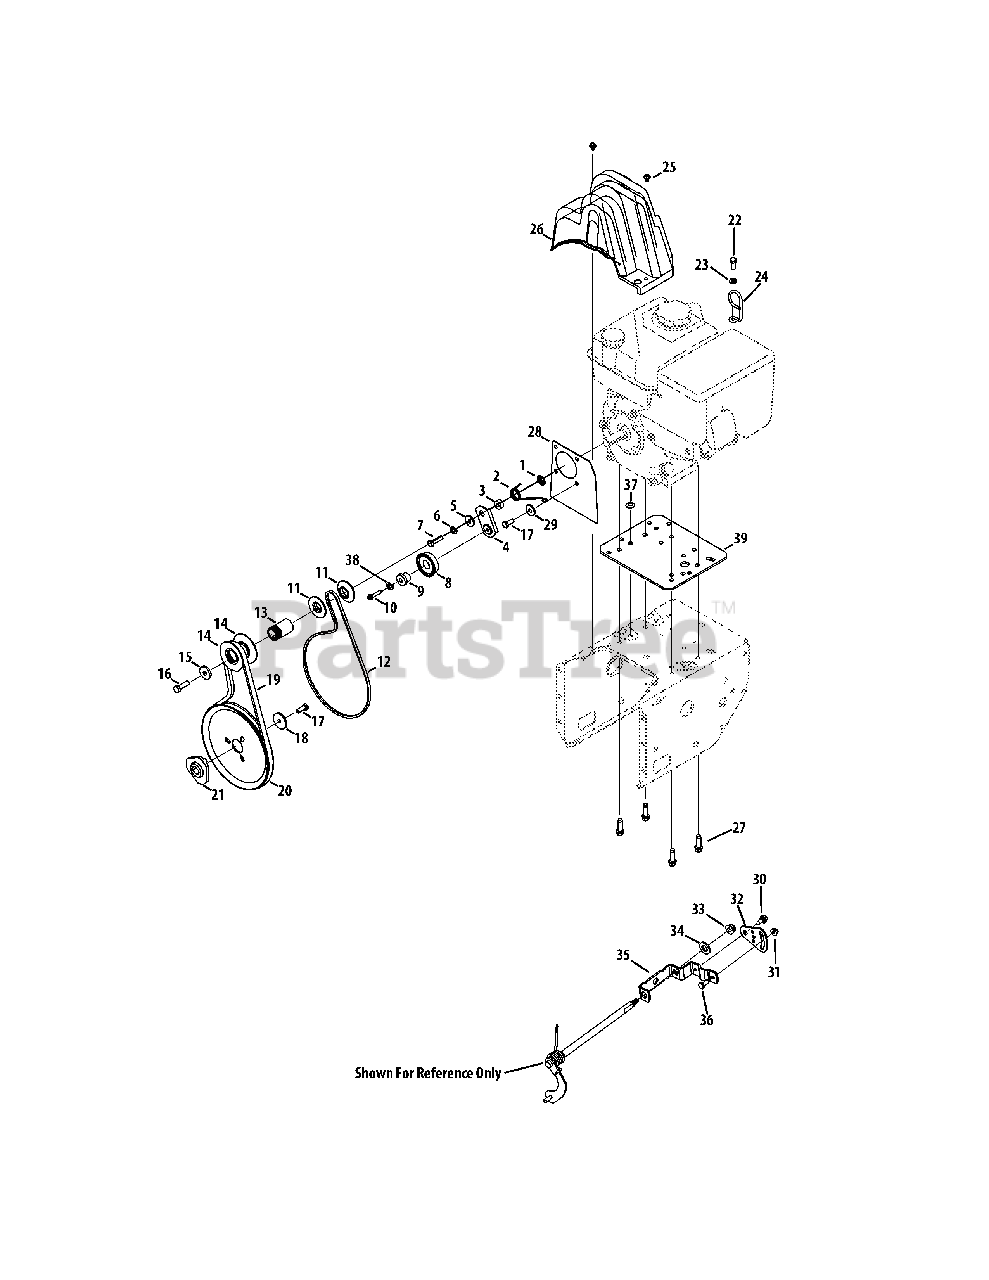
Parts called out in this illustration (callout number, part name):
1	Push-On Nut
2	Torsion Spring, .850 ID x .333
3	Spacer, .340 x .750 x .330
4	Idler Bracket
5	Shldr. Spacer, .3175 ID x .500 x .0975
6	Lock Washer, 5/16
7	Hex Screw, 5/16-24 x 1.25
8	Idler Pulley
9	Shoulder Spacer, .260 x .785 x .538
10	Hex Washer Screw, 1/4-20 x 1.250
11	Pulley Half, 3/8-V x 1.7160 OD
13	Spacer, .875 ID x 1.185 OD
14	Pulley Half, 4L-V x 2.600 OD
15	Flat Washer, .406 x 1.25 x .157
16	Hex Screw, 3/8-24 x 1.25
17	Hex Lock Screw, 5/16-24 x .875
18	Flat Washer, .34 x 1.50 x .150
19	Belt
20	Auger Pulley
21	Adapter Pulley
22	Hex Screw, M8-1.25 x 20
23	Flat Washer, .330 x .630 x .0635
24	Cable Control Wire
25	Hex Washer Screw, 1/4-20 x .375
26	Belt Cover
27	Hex Washer Screw, 3/8-16 x 1.250
28	Cover Plate
29	Shoulder Spacer
30	Shoulder Screw, .368 x .113 x 1/4-20
31	Flange Lock Nut, 1/4-20
32	Speed Selector Pivot Bracket
33	Flange Lock Nut, 5/16-18
34	Flat Washer, .469 x .875 x .105
35	Speed Selector Shift Bracket
36	Hex Screw, 1/4-20 x .620
37	Plug, 3/8 ID
38	Lock Washer, 1/4
39	Engine Plate
